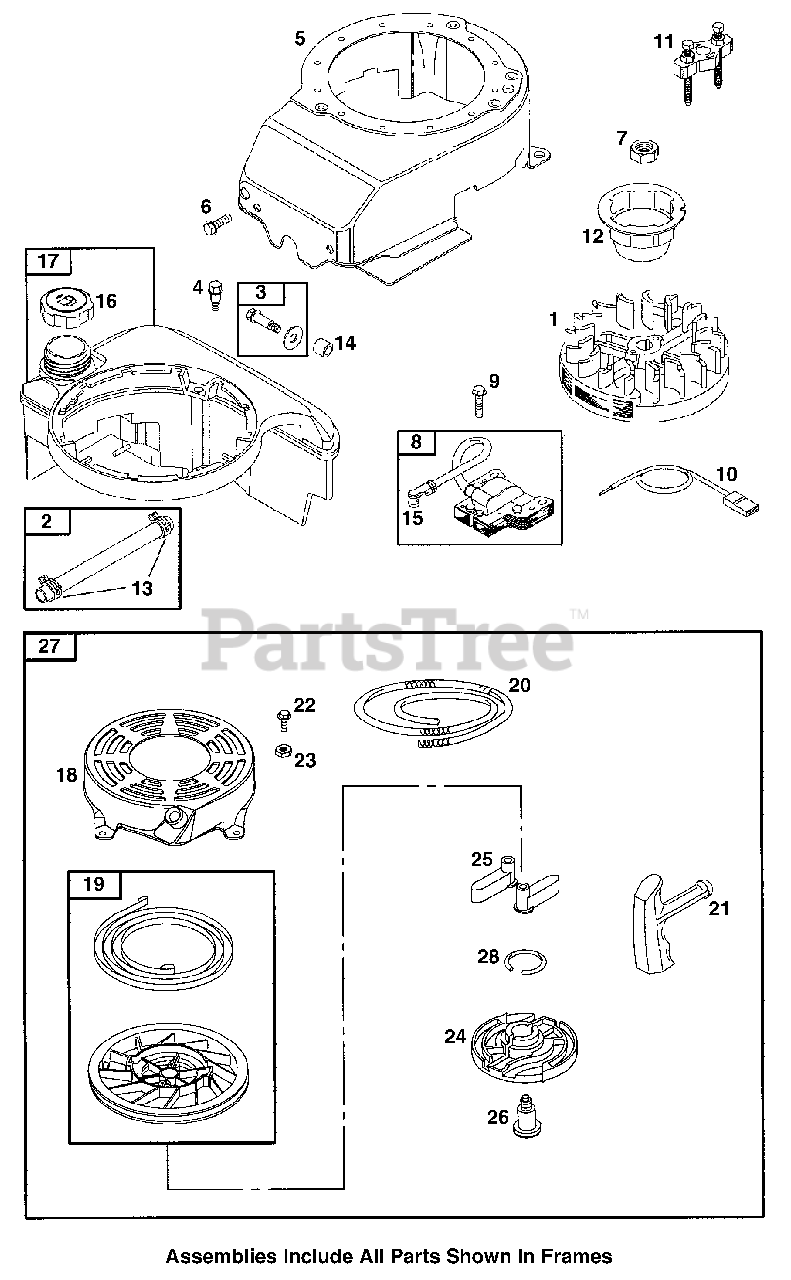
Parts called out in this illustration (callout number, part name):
1	Flywheel
2	Fuel Line
3	Washer Kit Screw
4	Shoulder Screw
5	Blower Housing
6	Hex Screw
7	Flywheel Nut
8	Magneto Armature
9	Hex Screw
10	Stop Wire
11	Flywheel Puller
12	Flywheel Cup
13	Hose Clamp
14	Fuel Tank Spacer
15	Cable Terminal
16	Fuel Tank Cap
17	Fuel Tank
18	Rewind Starter Housing
19	Starter Pulley
20	Starter Rope
21	Starter Rope Grip
22	Hex Screw
23	Hex Nut
24	Pawl Friction Plate
25	Rachet Pawl
26	Shoulder Screw
27	Rewind Starter
28	Friction Spring
